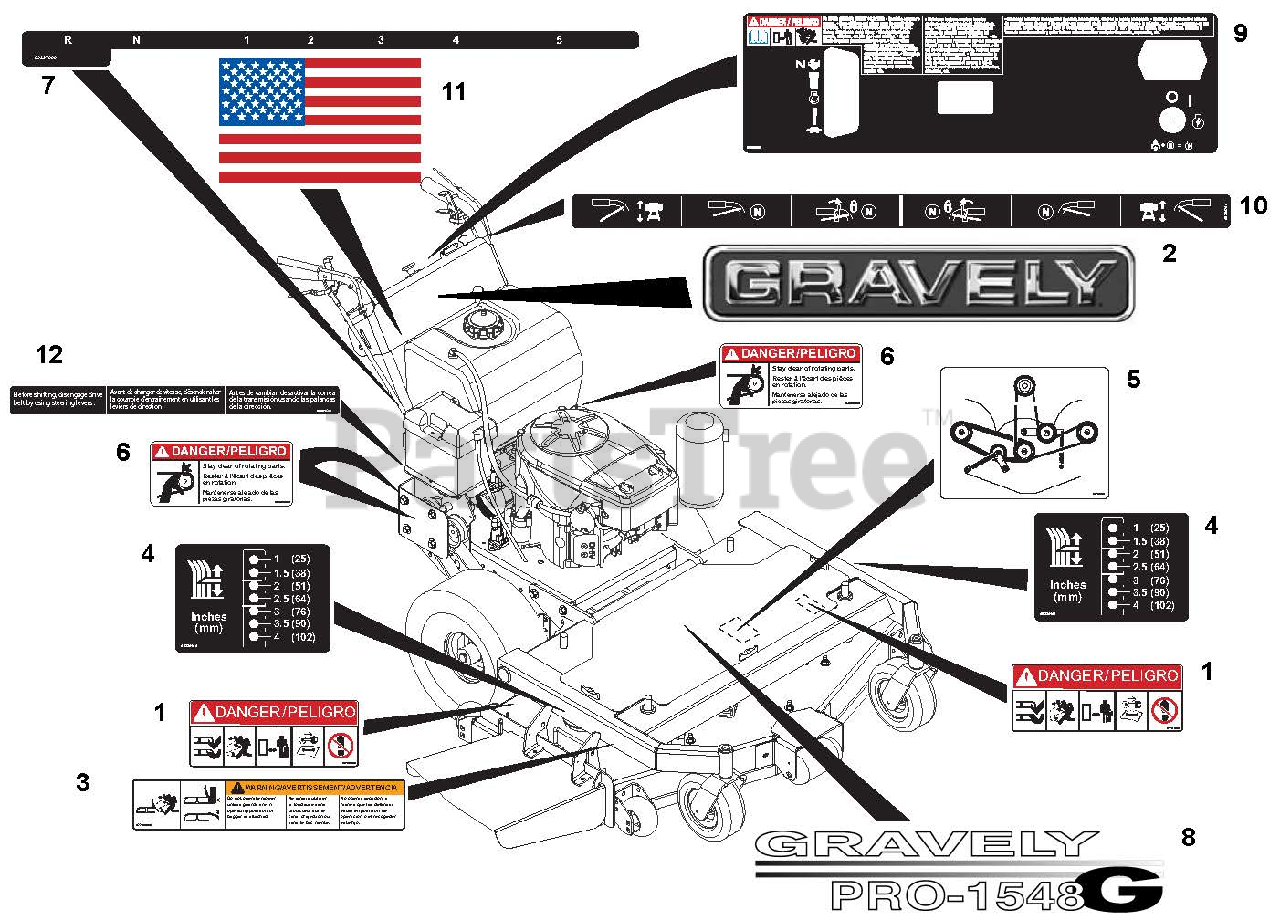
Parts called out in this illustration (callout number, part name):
1	Decal, Mower Pan Head Danger
2	Decal- 15" Gravely Logo
3	Decal, Warning
4	Decal-Height of Cut- Floating
5	Decal-Belt Diagram-3 Spindle
6	Decal-Danger-Belt Rotating
7	Decal-Shift Lever
8	Decal-Pro 1548G
9	Decal, Control GR15
10	Decal, Steer Levers
11	Decal, American Flag
12	Decal, Declutch
